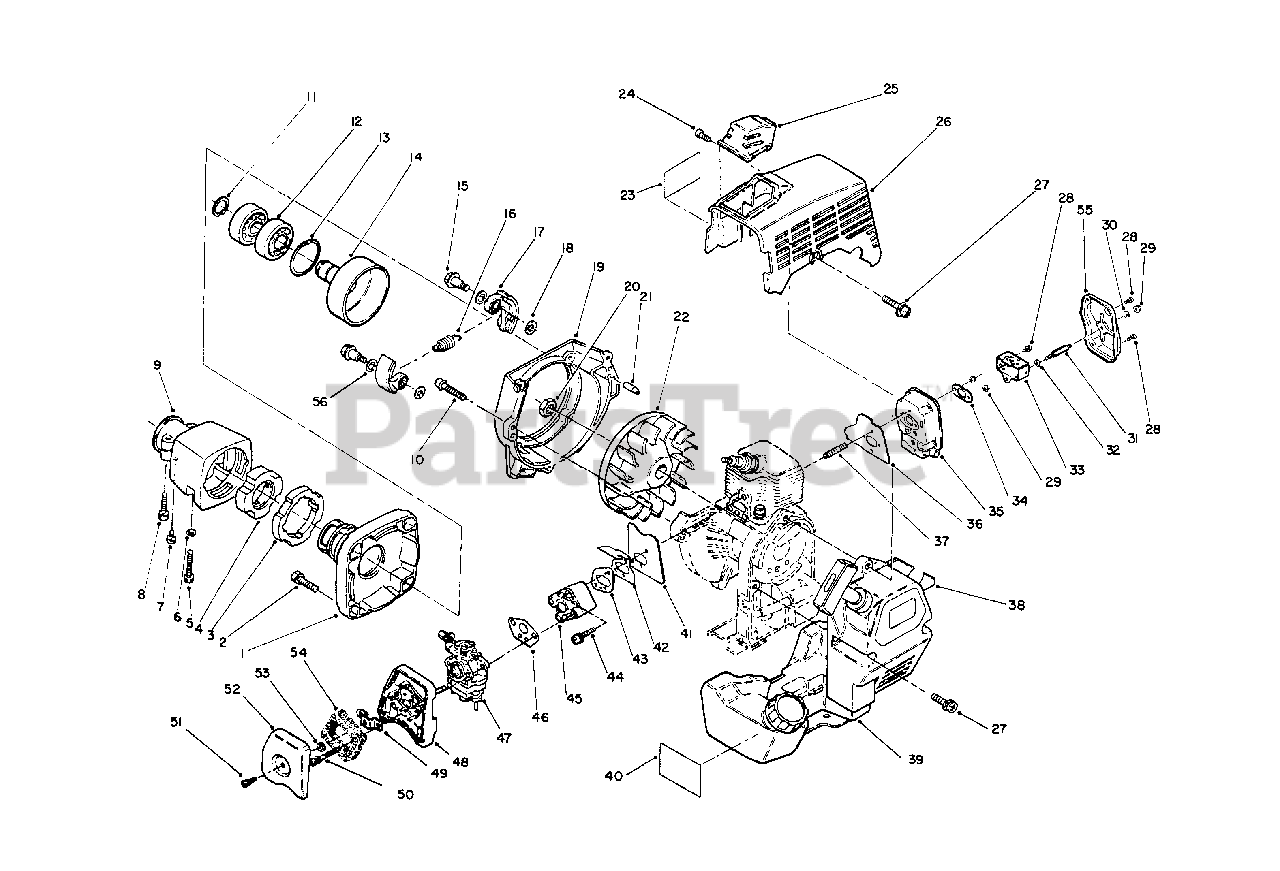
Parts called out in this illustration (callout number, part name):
1	Case-Clutch
2	Bolt/Washer
5	Screw/Washer
6	Washer-Lock
7	Screw/Washer
8	Bolt/Washer
10	Screw/Washer
11	Ring-Retaining
12	Bearing-Ball
13	Ring-Retaining
14	Drum-Clutch
15	Bolt-Clutch
17	Shoe-Clutch
19	Case-Fan
20	Nut-Conical
21	Pin-Dowel
23	Decal-Hot
24	Screw/Washer
25	Guard-Spark Plug
26	Cover-Engine
28	Screw/Washer
29	Nut-Flange Lock
31	Spacer-Threaded
34	Plate
36	Gasket-Muffler
38	Starter-Recoil
39	Tank Assembly-Fuel
40	Decal-Fuel Mix
41	Gasket-Insulator
43	Gasket-Insulator
44	Screw/Washer
45	Insulator
46	Gasket-Carburetor
47	Carburetor Assembly
48	Case-Air Cleaner
50	Screw/Washer
51	Screw/Washer
52	Cover-Air Cleaner
53	Nut-Push
54	Element-Air Cleaner
55	Cover-Muffler
56	Washer-Wave
